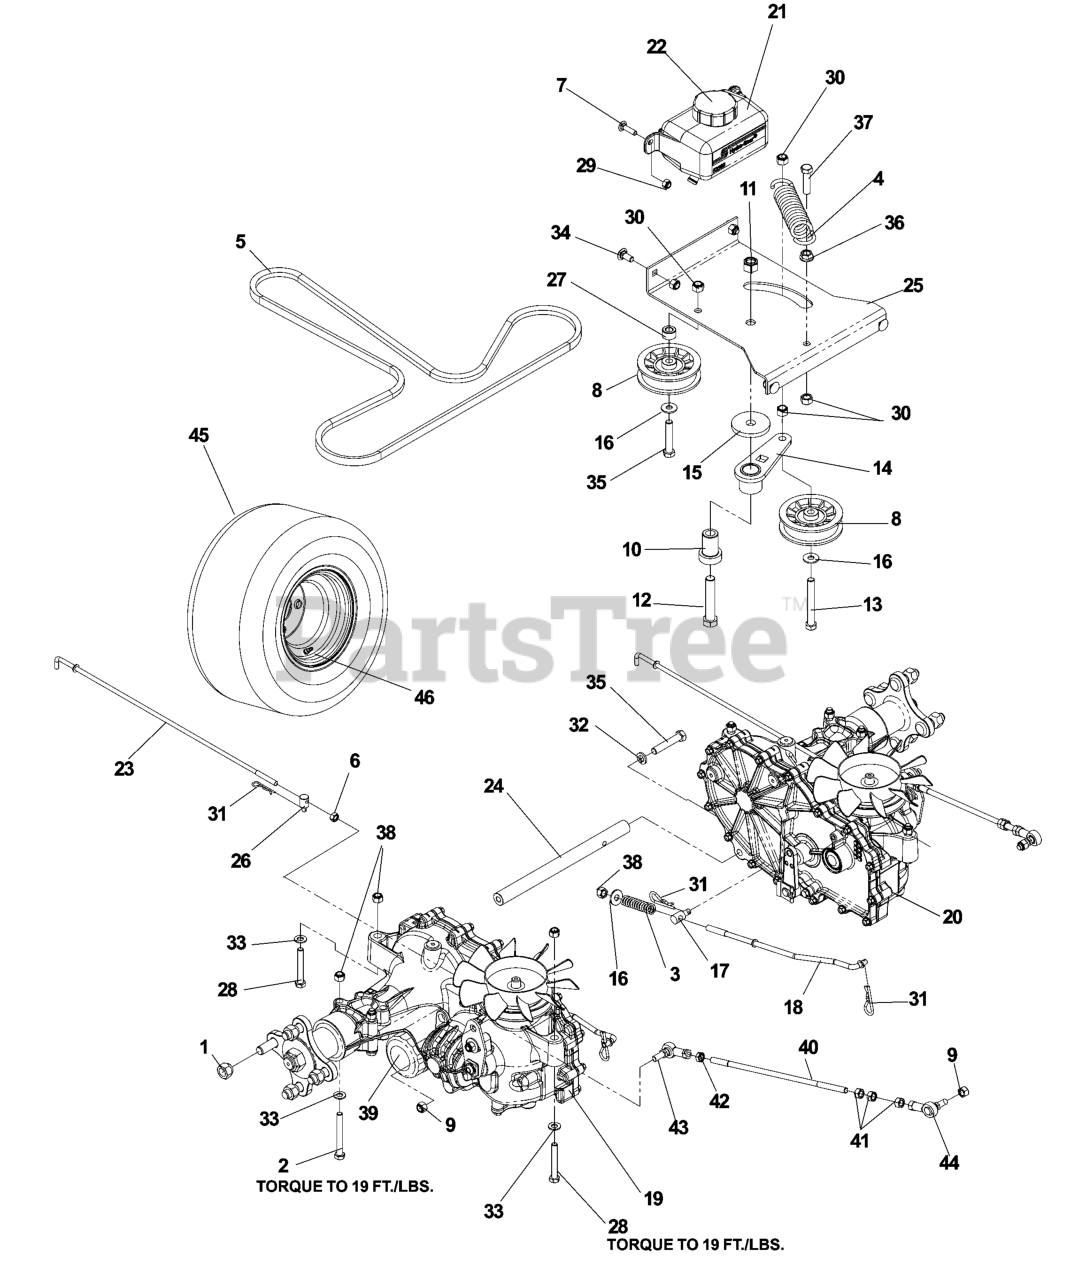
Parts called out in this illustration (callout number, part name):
1	LUG NUT 1/2F
2	HCS 5/16C X 2-3/4
5	PUMP BELT
6	NUT 1/4-28 HEX ZD
7	RHSNB, 1/4-20 X 1, GR5
8	PULLEY, IDLER
9	NUT 5/16F NYLOC
10	IDLER SPINDLE
11	NUT 1/2-13 HEX NYLOC ZD
12	HCS 1/2C X 2 3/4
13	TAPBOLT, 3/8C X 3
14	IDLER ARM WELDMENT
15	HEAVY WASHER
16	WASHER 5/16 FLAT
17	BRAKE SWIVEL
18	BRAKE LINKAGE, LOWER
19	HG_ZT2800, RT, NON CHARGED
20	HG_ZT2800, LT, NON CHARGED
21	HG_EXPANSION TANK W/CAP
23	BYPASS LINKAGE
24	2800 CROSS SUPPORT
25	IDLER PULLEY PLATE
26	SWIVEL, 1/4-28
28	CAPSCREW
29	NUT 1/4-20 NYLOC
30	NUT 3/8-16 NYLOC
31	HAIRPIN #2
32	SLW 3/8 STD
33	FLAT WASHER 5/16 SAE
34	BOLT 5/16C X 3/4" CARRIAGE
35	HCS 3/8C X 2
36	NUT 3/8C WHIZ
37	HCS 3/8C X 1 1/2
38	NUT 5/16 NYLOC
39	HG_FILTER, ZT4800
40	DRIVE LINKAGE
41	NUT 5/16F
42	NUT 5/16F LEFTHAND
43	SPHERICAL ROD END, LH
44	SPHERICAL ROD END, RH
45	WHEEL TIRE ASM 18X8.5 - 8
46	VALVE STEM TR-412
